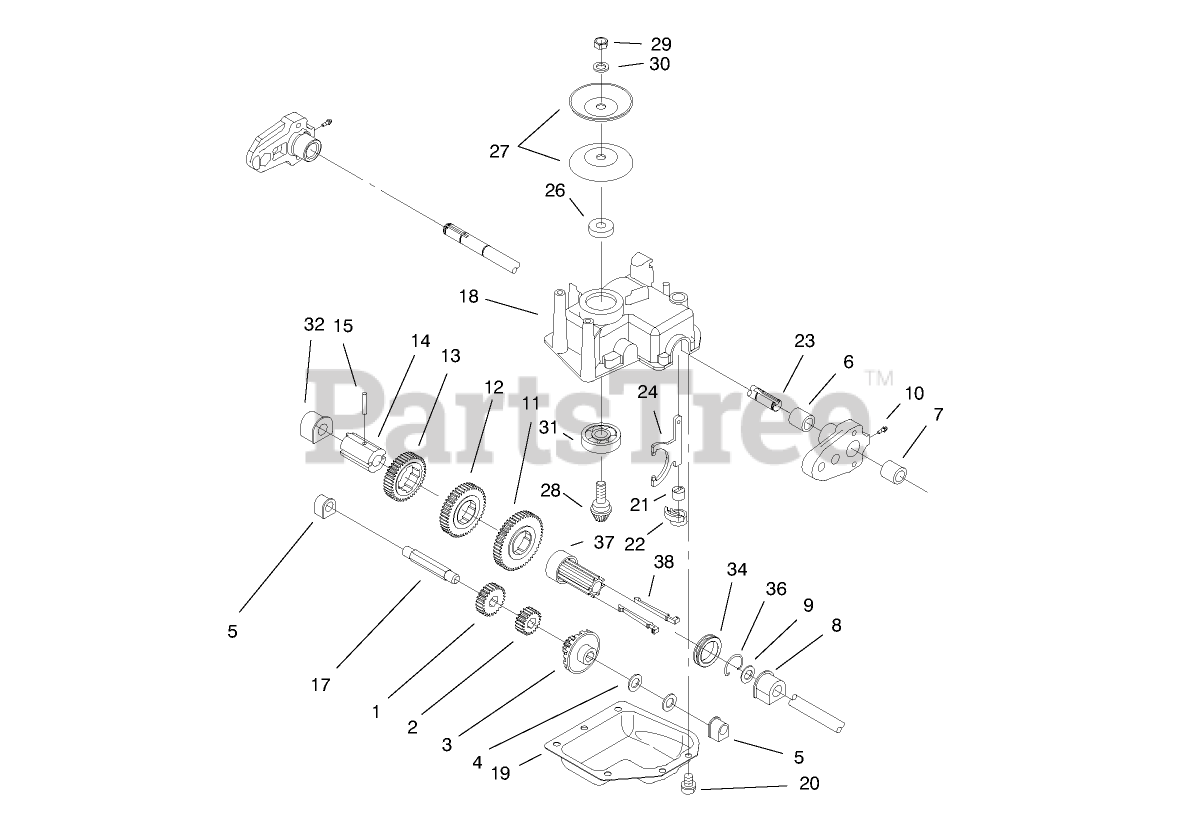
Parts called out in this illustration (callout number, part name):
1	PINION-25T
2	PINION-20T
4	WASHER-THRUST
5	BUSHING
6	BUSHING
8	BUSHING-OUTPUT
9	WASHER-PLAIN
10	FITTING-GREASE
11	GEAR-49T
12	GEAR-44T
13	GEAR-39T
14	SLEEVE-GEAR
15	PIN-SPRING
18	CASE-GEAR, UPPER
20	SCREW-HWHTF
21	BUSHING-YOKE
22	RETAINER-FORK, SHIFT
23	SHAFT-OUTPUT
24	YOKE-SHIFT
26	SPACER
29	NUT-HEX
30	WASHER-FLAT
31	BEARING-BALL
32	BUSHING
34	COLLAR-SHIFT
36	CLIP-SPRING
37	SLEEVE-KEY, SHIFT
38	KEY-SHIFT
